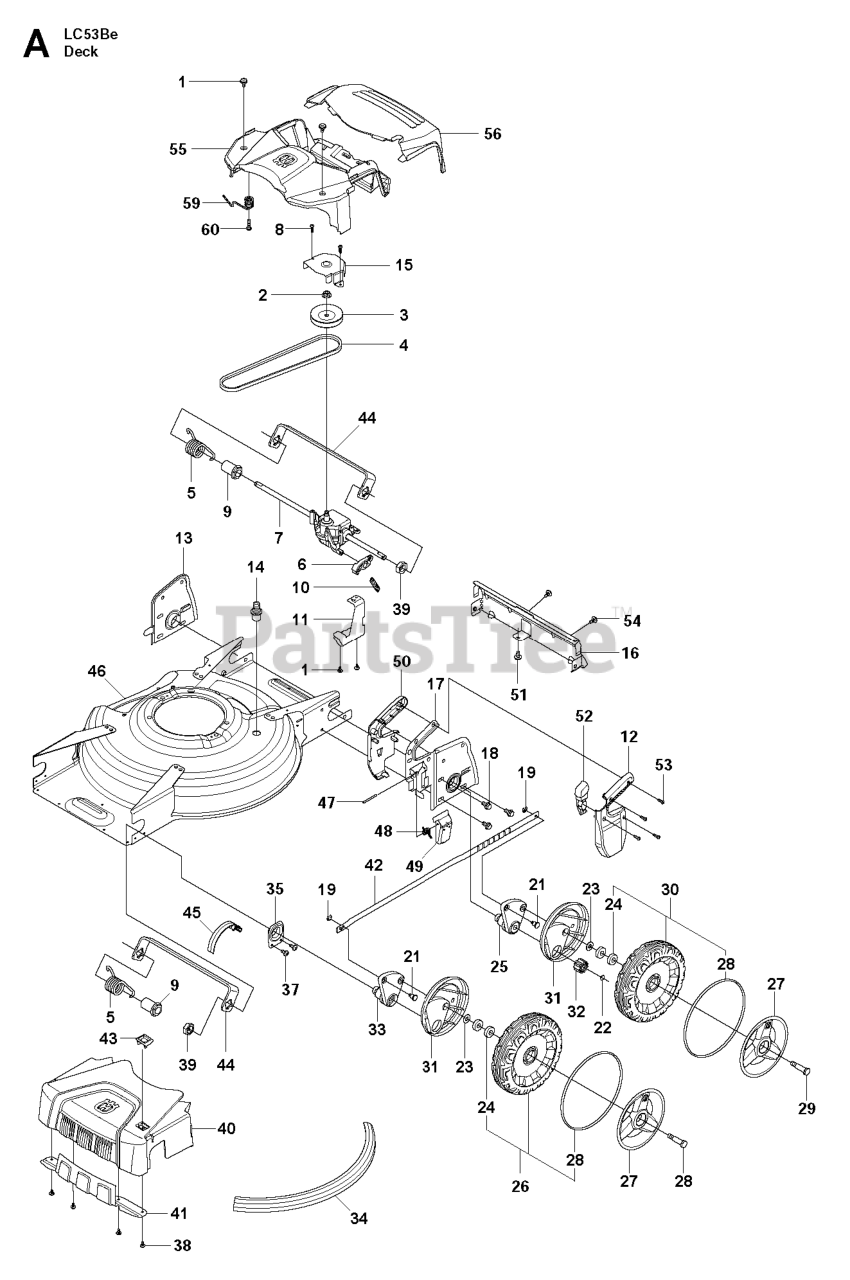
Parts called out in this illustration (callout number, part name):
1	STARTER ASSY
4	STARTER PULLEY
5	STARTER ROPE
6	STARTER PAWL
8	RETAINER
9	WASHER
13	STARTER PAWL
14	NUT
